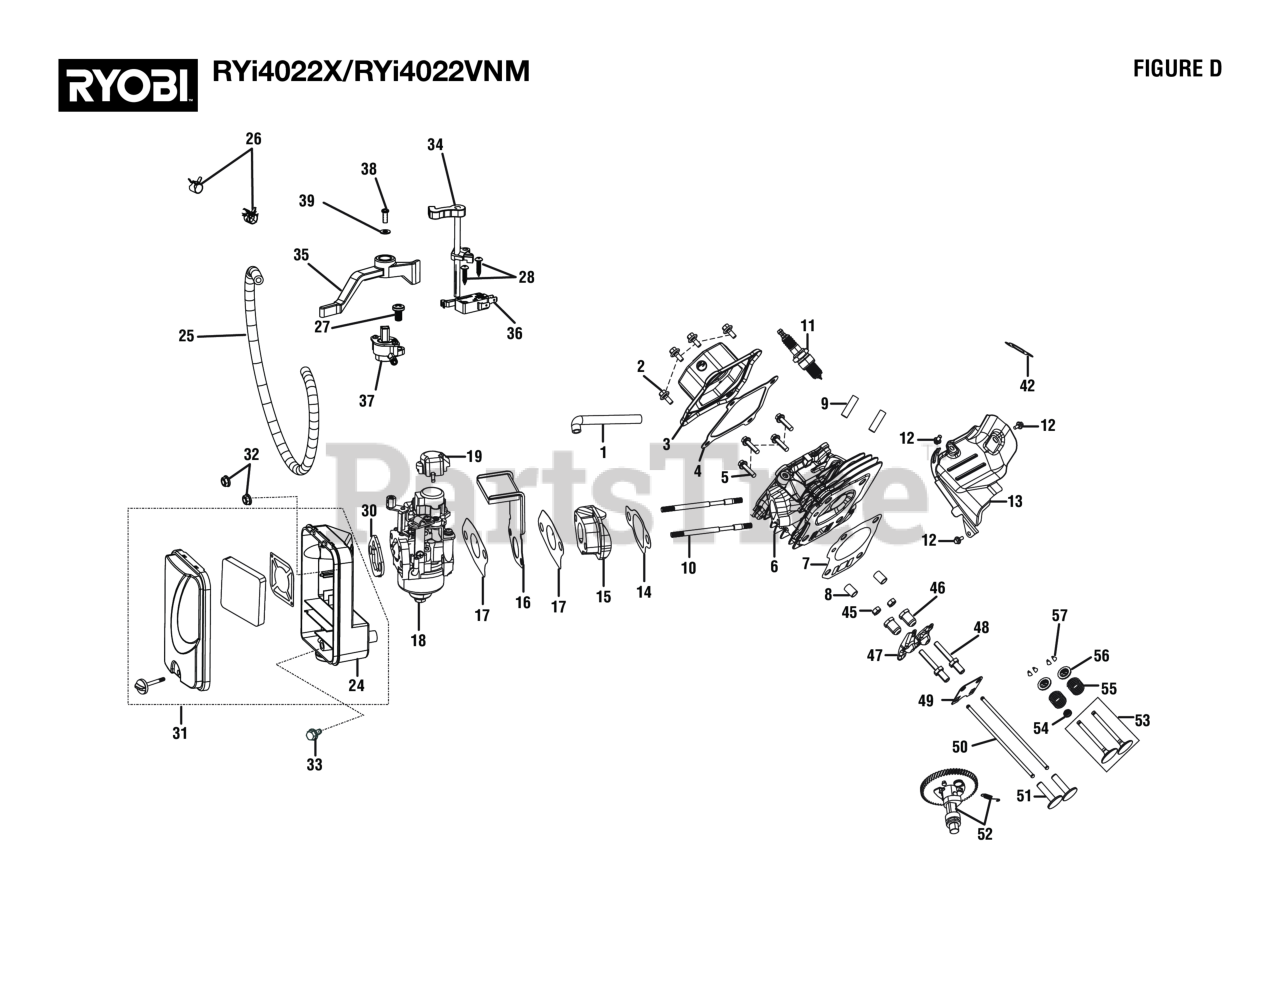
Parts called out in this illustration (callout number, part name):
2	Bolt (need size)
3	Cylinder Head Cover Sub-assembly
4	Cylinder Head Cover Gasket
5	Bolt (Cylinder Head)
6	Cylinder Head Assembly
7	Cylinder Head Gasket
12	Bolt
13	Cylinder Body Shroud
14	Carburetor Insulator Gasket
15	Carburetor Insulator Plate
16	Step Motor Heat Shield
17	Carburetor Gasket
18	Carburetor Assembly
24	Engine Air Box
25	Fuel Hose (300 mm)
26	Fuel Line Clamp (3/8 in.)
27	Screw (M6 x 10 mm, Pan Hd.)
28	Screw (St 2.9 x 16 mm, Pan Hd)
30	Air Cleaner Gasket
31	Engine Air Box Assembly
32	Governor Support Assembly
34	Choke Lever
35	Control Lever
36	Engine Stop Switch
37	Fuel Valve
38	Screw (M4 x 10 mm, Phillips Pan Hd.)
39	Washer (ID4.3 x OD10 x 0.9t)
42	Air Valve Gasket
46	Valve Adjustment Nut
48	Valve Adjustment Bolt
49	Lifter Stopper Plate Sub-assembly
52	Camshaft Assembly
56	Valve Spring Seat
57	Valve Lock Clamp
